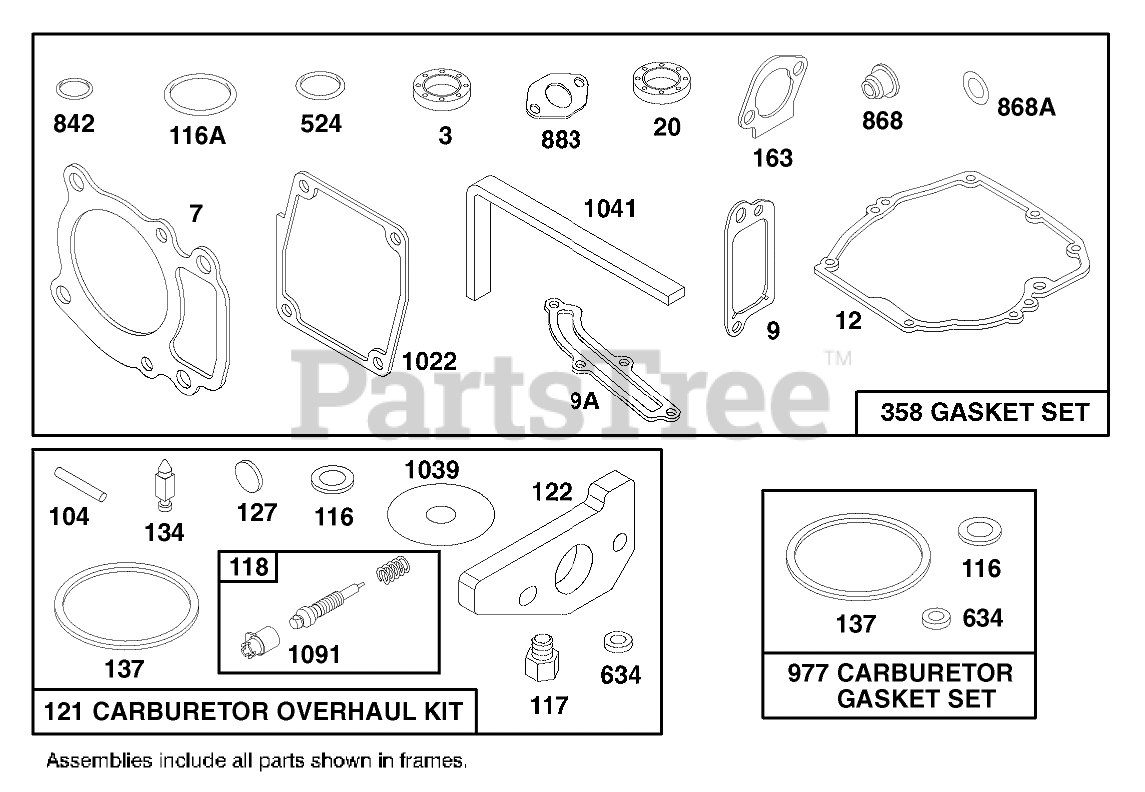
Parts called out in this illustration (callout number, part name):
3	SEAL - OIL
7	CYLINDER HEAD GASKET
9	BREATHER GASKET
9A	GASKET-BREATHER
12	ENGINE BASE GASKET
20	SEAL-OIL
104	FLOAT HINGE PIN
116	SEALING GASKET
116A	O RING SEAL
118	VALVE/SPRING - NEEDLE
121	KIT-CARBURETOR OVERHAUL
122	ADAPTER ASSEMBLY
127	PLUG - WELCH
134	Valve-Inlet (Includes Seat)
137	FLOAT BOWL GASKET
163	AIR CLEANER GASKET
358	GASKET SET
524	O-RING
634	SEAL WASHER
842	O-RING
868	SealAssy-Valve
868A	Seal-Valve
883	EXHAUST GASKET
977	CARBURATOR GASKET SET
1022	ROCKER COVER GASKET
1039	FLOAT LIMITER
1041	SEAL - FOAM
1091	CAP - LIMITER
